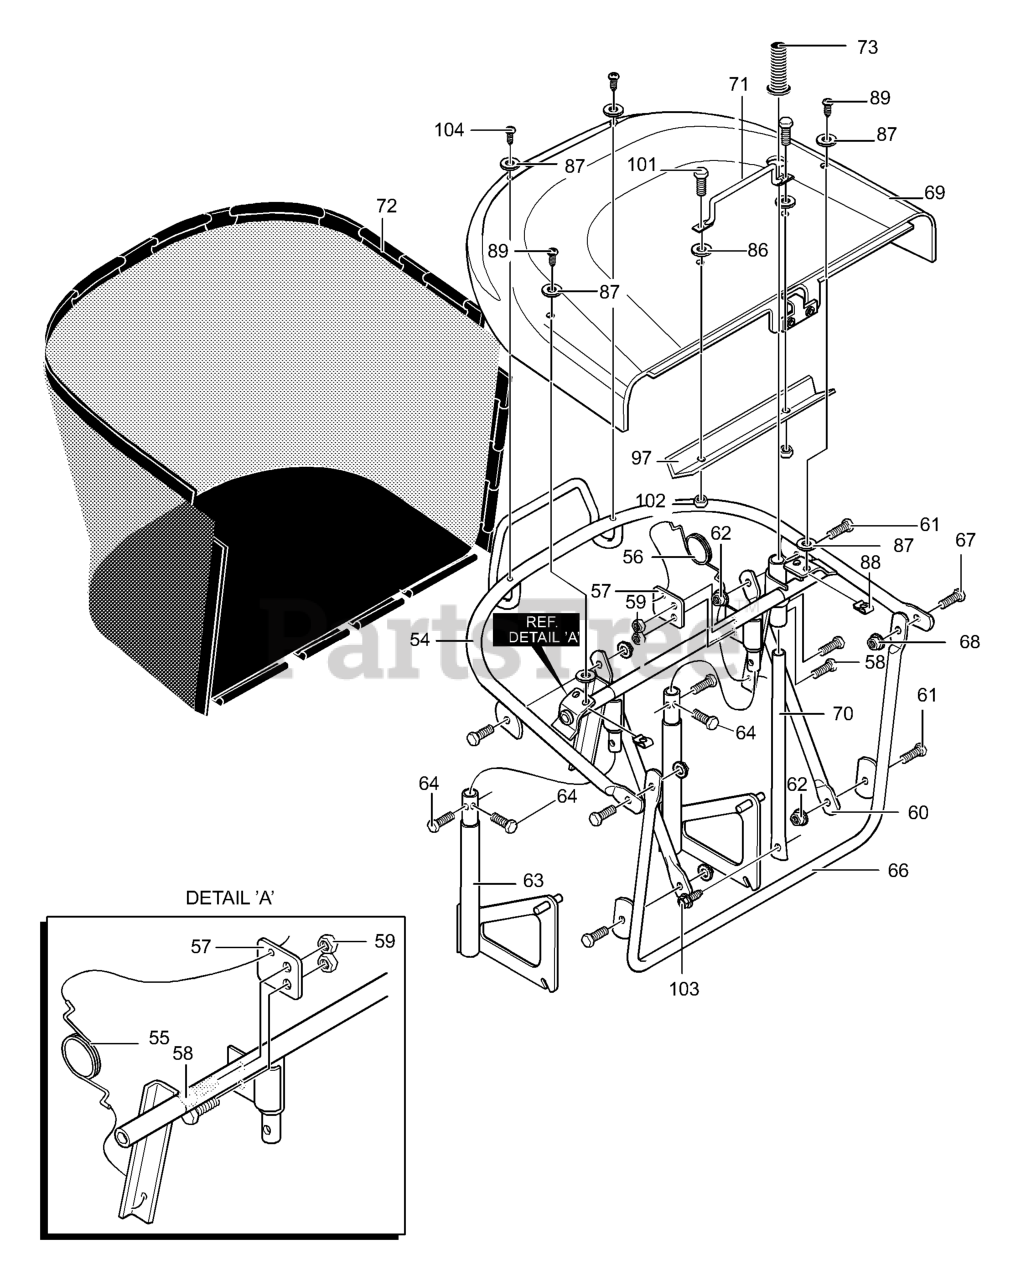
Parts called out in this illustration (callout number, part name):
54	Asm. Weld Upper Frame
55	Spring, Torsion RH
56	Spring, Torsion LH
57	Bracket, Spring Collector
58	Screw, 1/4-20x.50
59	Nut, 1/4-20
60	Brace, Frame Collector
61	Screw, 1/4-20x.62
62	Nut, 1/4-20
63	Weld Asm. Support Collector
64	Screw, 1/4-20x1.50
66	Weld Asm. Front Frame Collect
67	Screw, 1/4-20x.62
68	Nut, 1/4-20
69	Top Collector Assembly
70	Handle, Dump Collector
71	Handle, Reba Collector
72	Reba Collector Bag
73	Rubber Grip
86	Washer
87	Washer
88	Nut, 1/4-20 Tinnerman
89	Screw, 1/4-20x.63
97	Brace, Bagger
101	Screw, 1/4-20x1.50
102	Nut, 1/4-20
103	Screw, #12x.50
104	Screw, #12x.50
